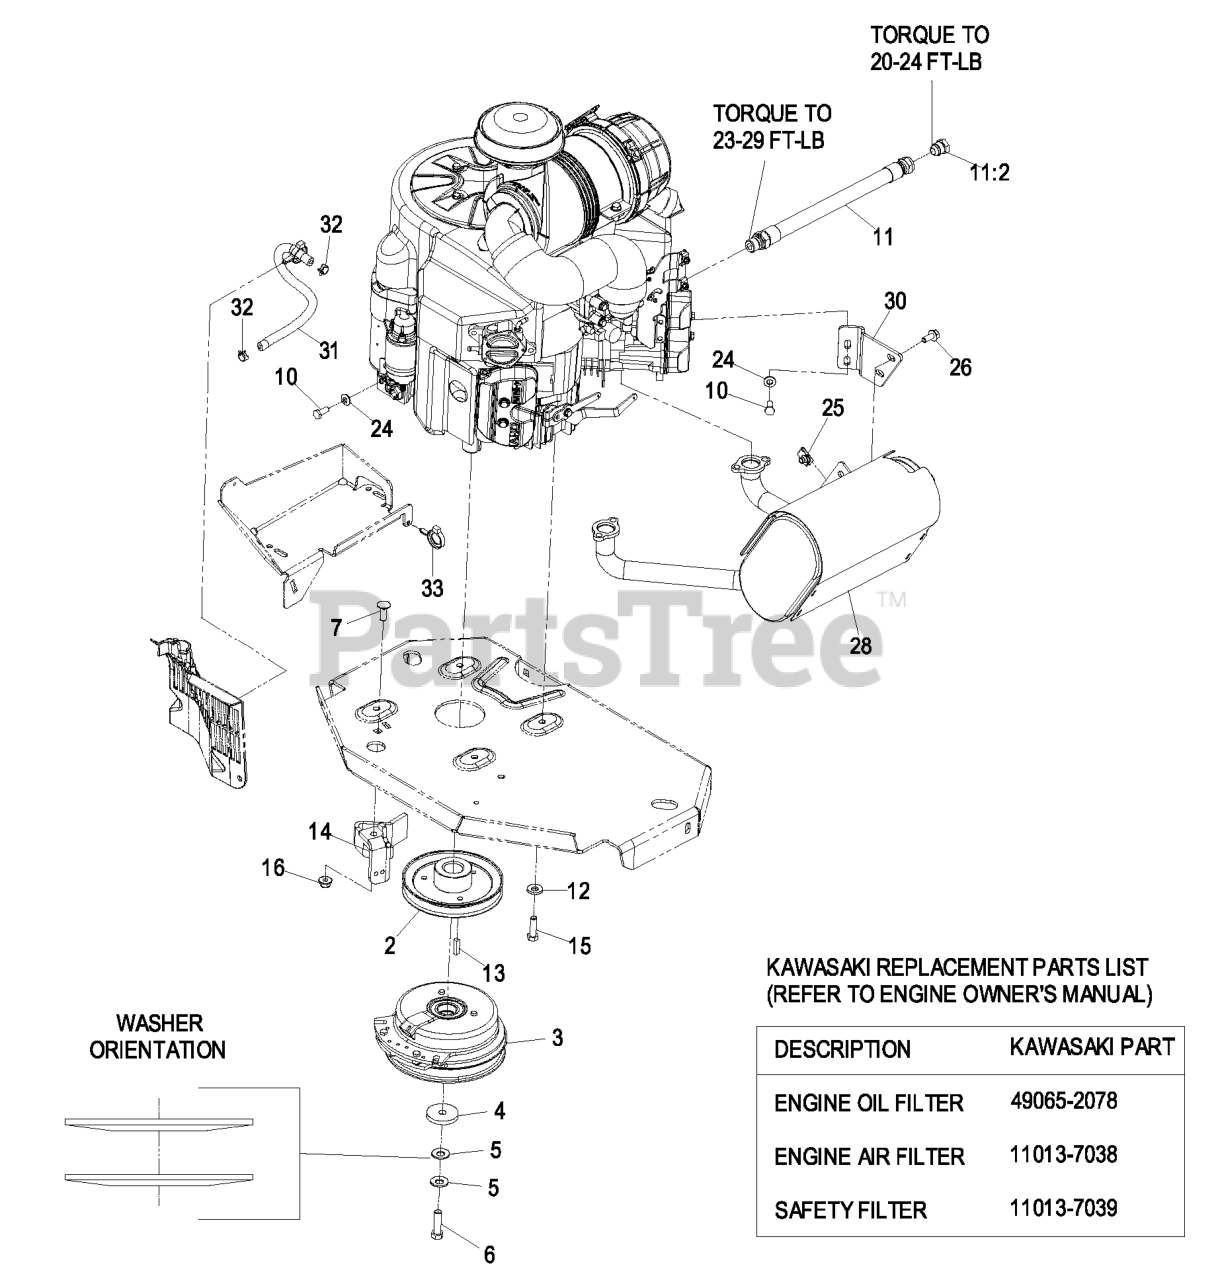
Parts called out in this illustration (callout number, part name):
2	SHEAVE
3	CLUTCH KIT
4	WASHER-CLUTCH
5	WASHER-SPRING
6	SCREW-HH 7/16-20 X 1 1/2 W/LOCTITE
7	SCREW-CARR
10	SCREW-HH
12	WASHER-BELLEVILLE
14	CLUTCH-ANCHOR
15	SCREW-HH
16	NUT-HF, NI
24	WASHER-SPRING
26	SCREW-HHF
28	MUFFLER
30	BRACKET-MUFFLER
31	HOSE-FUEL
32	CLAMP-HOSE
33	CLAMP-HOSE
